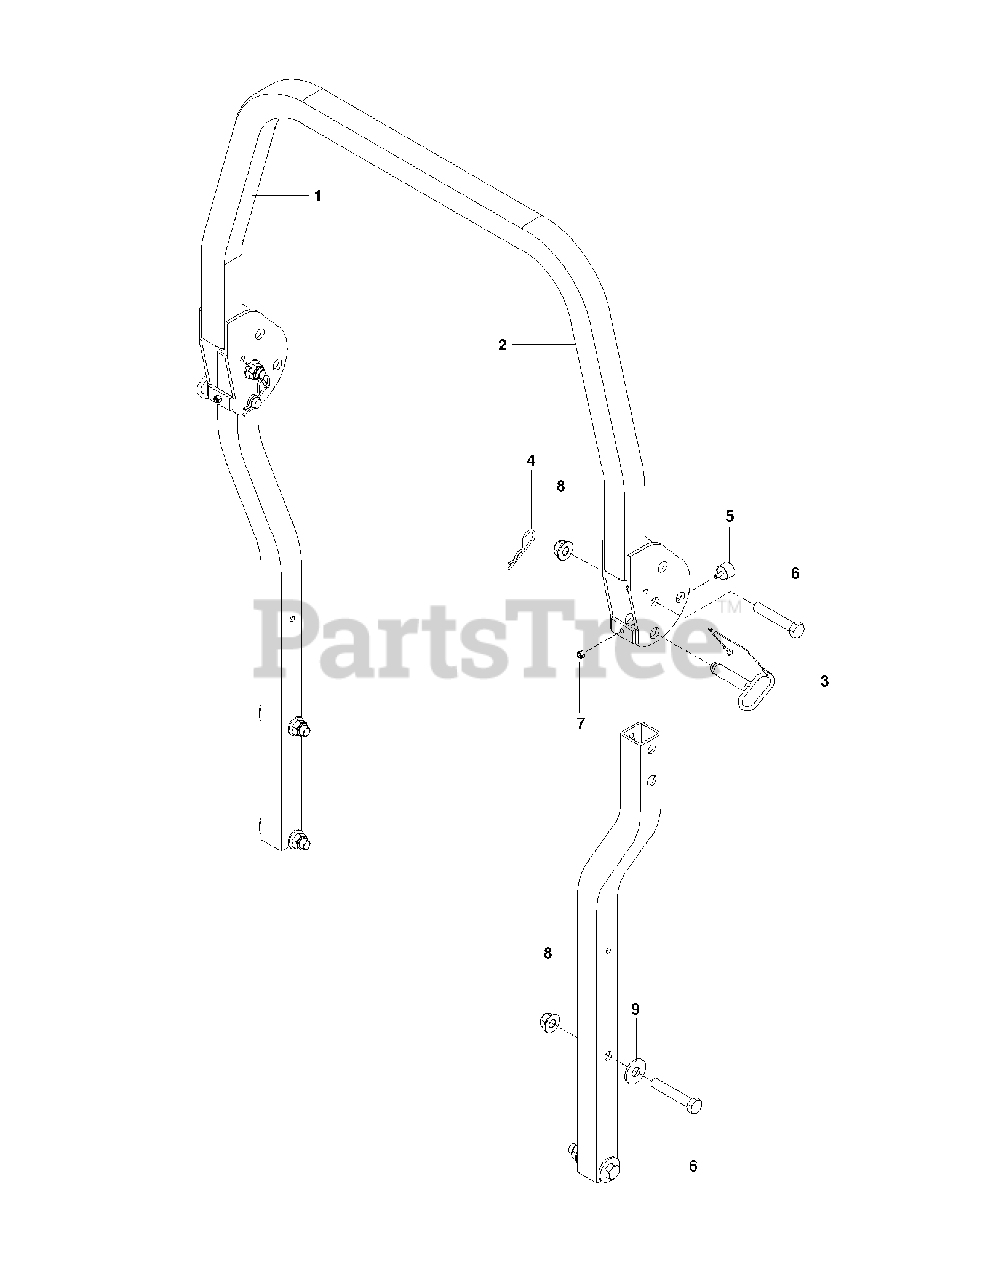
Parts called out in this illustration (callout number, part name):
1	DECAL, ROPS, WARNING
3	PIN, ROPS
4	PIN HAIR .148 X 2-15/16 #210
5	BUMPER, MALE STUD, 1/4-20
6	5/8-11 X 3-1/2 HHB GRADE 5
7	NUT 1/4-20 NYLOC
8	NUT 5/8-11 FLG NYLOC ZD
9	WASHER, 5/8 FLAT
